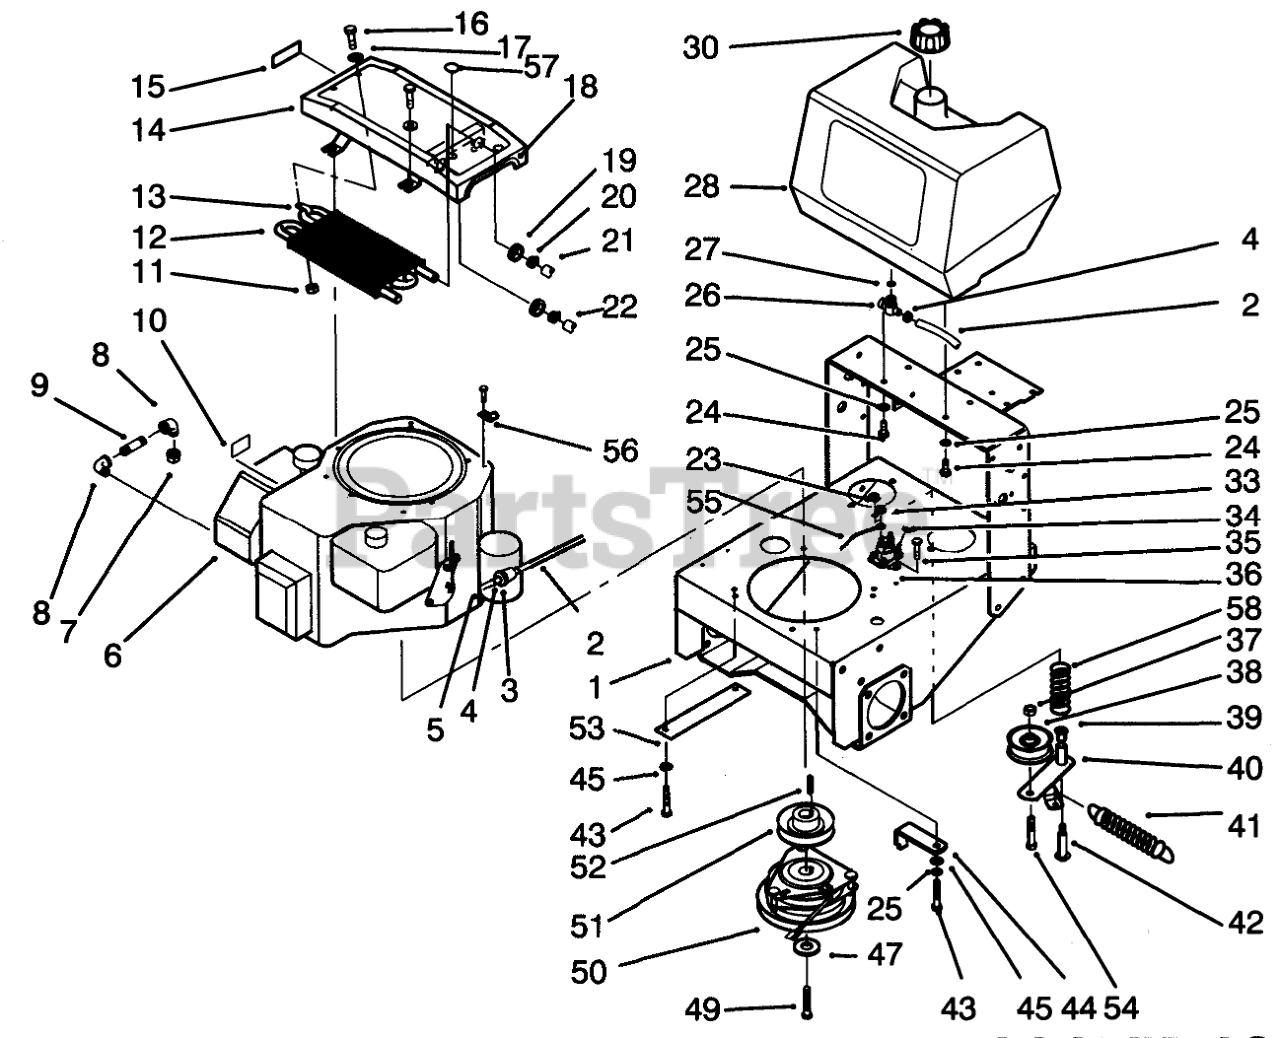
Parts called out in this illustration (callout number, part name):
1	Frame
2	HOSE-FUEL
3	FILTER-FUEL
4	CLAMP-HOSE
5	HOSE-FUEL
6	Engine-14 H.P. Kohler
7	CAP-PIPE
8	ELBOW-STREET, 90 DEG
9	NIPPLE
10	DECAL-SURFACE, HOT
11	NUT-LOCK, NI
12	Cooler-Oil
13	CLAMP-R
14	Mount-Cooler
15	DECAL-FUEL SHUT OFF
16	SCREW-HH
17	WASHER-FLAT
18	TRIM-MOUNT, COOLER
19	GROMMET
20	CLAMP-HOSE
21	HYDRAULIC HOSE ASM
22	HYDRAULIC HOSE ASM
23	NUT-LOCK
24	SCREW-HH
25	WASHER-LOCK
26	VALVE-FUEL
27	O-RING
28	FUEL TANK
30	GAS CAP ASM
33	NUT-KEPS
34	NUT-KEPS
35	SCREW-HWH
36	SOLENOID
37	NUT-LOCK, NI
38	PULLEY
39	BUSHING-FLANGE
40	Idler Assembly (Incl. Ref. #39)
41	SPRING
42	BOLT-WHEEL
43	SCREW-HH
44	Retainer-Clutch
45	WASHER-PLAIN
47	WASHER
49	SCREW-CLUTCH
50	CLUTCH/BRAKE
51	Pulley
52	KEY-SQUARE
53	Guard-Pulley
54	SCREW-HH
55	WIRE-SOLENOID/STARTER
56	CLAMP-R
57	PLUG-PLASTIC
58	SPRING-COMPRESSION
